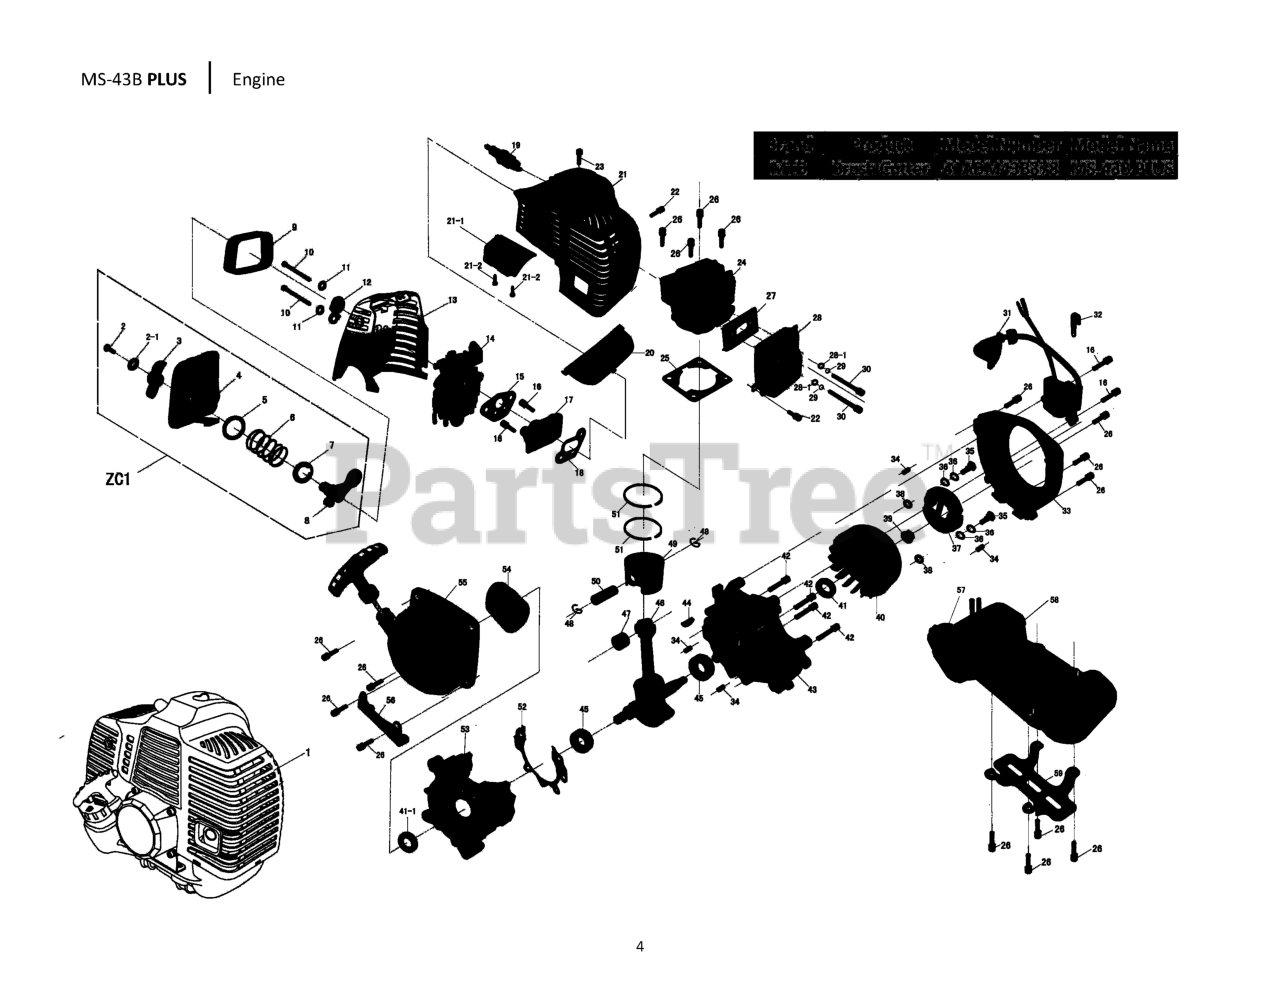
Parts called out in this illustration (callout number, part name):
1	Engine ASSY
2	Tapping screw
2-1	Flat washer
3	Knob of choke
4	Cover of air filter
5	washer of choke
7	washer for choke spring
9	Sponge-air filter
11	FLAT WASHER
12	Baffle of Choke
13	empty filter body
14	Carburetor
15	Washer of carburetor
16	COMBINATION SCREW
17	Boot-intake
18	Washer of boot-intake
19	Spark plug
20	Heat pad of fuel tank
21	Cover of cylinder(186C-2)
21-1	BAFFLE-FAN
22	Combination screw
24	Cylinder
25	Washer of cylinder
26	COMBINATION SCREW
27	Washer of muffler
28	Muffler
28-1	Flat washer
33	Side cover of crankcase
34	Round pin
35	Screw of clutch
37	Clutch ASSY
38	Flat washer
40	Flywheel
41	Oil seal
41-1	OIL SEAL
42	Combination screw
43	Right crankcase
44	Woodruff key
46	Crankshaft ASSY
47	NEEDLE BEARING
48	Snap ring
50	Piston pin
51	Piston ring
52	Washer of crankcase
53	Left crankcase
54	Easy starter pulley
55	Easy starter ASSY
56	Fuel tank holder
57	Fuel cap Assy
58	Fuel tank ASSY
59	Fuel tank support
ZC1	Cover of air filter assy
